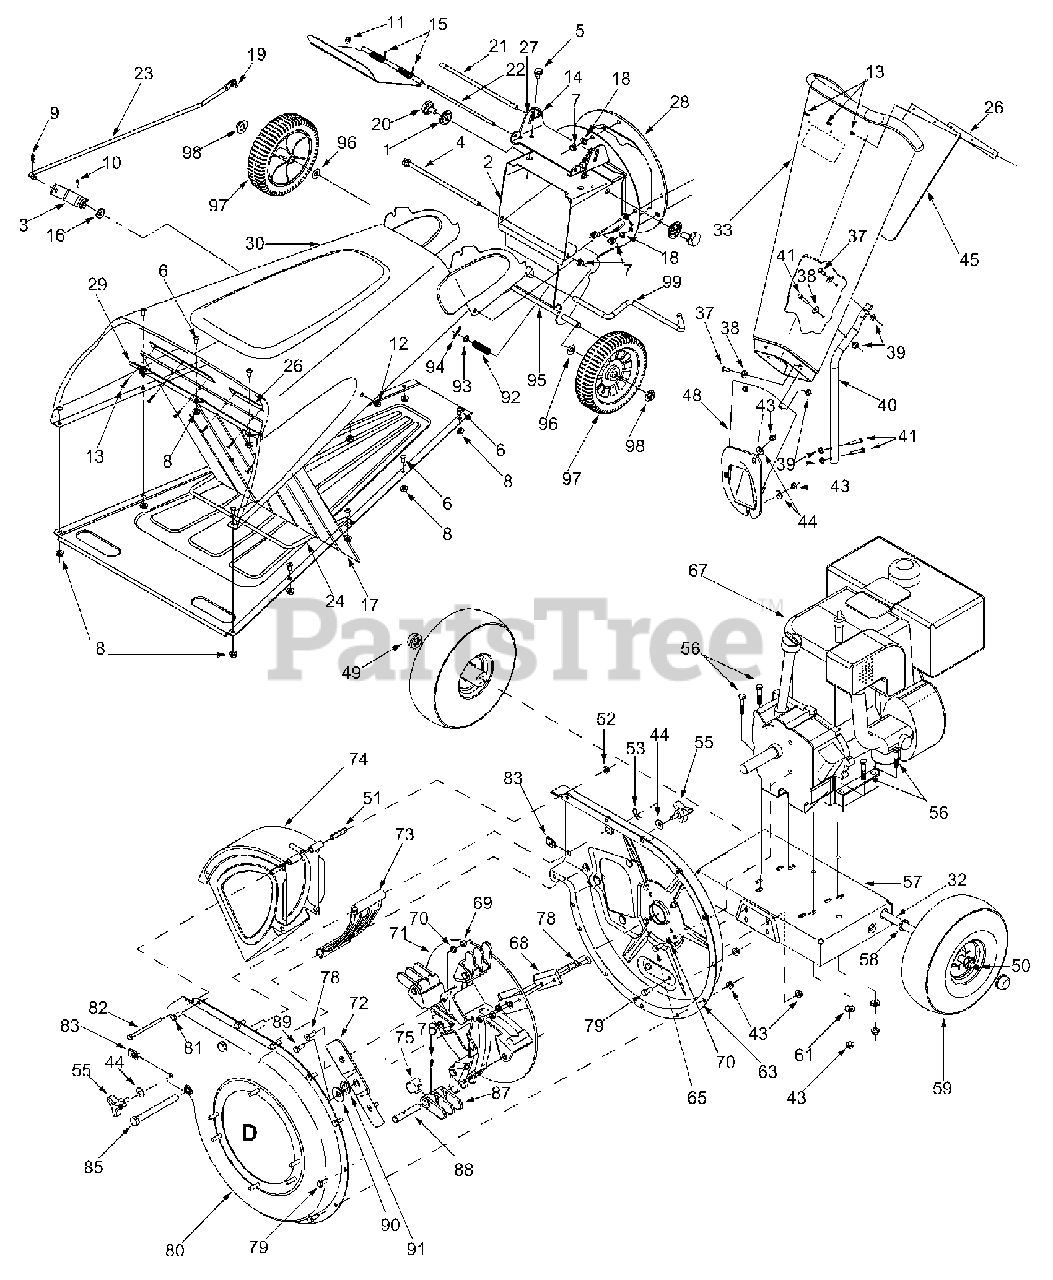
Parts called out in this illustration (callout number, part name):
1	Stop Washer
4	Hex Flange Bolt: 5/16-18 x 8.375" (Gr.5)
5	Hex Washer Head Self-Tapping Screw: 5/16-18 x 0.5"
6	Button-Head Screw 1/4-20 x 0.5"
7	Lock Nut: 5/16-18
8	Hex Flange Lock Nut: 1/4-20
9	Internal Cotter Pin
10	Spiral Pin
11	Cap Nut
12	Speed Cap Nut
13	Pop Rivet
14	Torsion Spring
15	Hopper Door Spring
16	Rubber Washer
17	Hopper Flap
18	Lock Washer
19	Shdr. Scr: .340 x .285 x 1/4-20
20	Shdr. Scr: .56 x .165 x 5/16-18
21	Rel. Rod: 5/16" dia.
22	Hopper Door Rod
23	Flap Retaining Rod
24	Flap Retaining Bail
32	Shredder Axle
33	Chipper Chute
37	Hex Bolt 1/4-20 x .625
38	Flat Washer .28 I.d. x .74 O.d.
39	Flanged Lock Nut
41	Hex Scr. 1/4-20 x .625 (Gr. 2)
43	Hex Nut 5/16-18 Thd. (Gr. 5)
44	Bell Washer .345" I.d. x .88"
45	Shredder Chute Flap
48	Chipper Chute Assembly
49	Push Cap 5/8" dia.
50	Air Valve
51	Chute Hinge Spacer
52	Hex Ctr. Lock Nut 1/4-20 Thd.
53	Internal Cotter Pin
55	Hand Knob
56	Hex Bolt 5/16-18 x 1.5"
58	Flat Washer 1.12 x .64 x .120
59	Wheel Assembly
61	Special Lock Washer
63	Flail Housing Ass'y. - Inner
65	Hex Bolt 5/16-24 x .75" Lg.
68	Chipper Blade
69	Hex Top Lock Nut 5/16-24 (Gr. 5)
70	Lock Washer 5/16" I.d.
71	Impeller assembly
72	Shredder Blade
73	Shredder Screen
75	Retaining Clip
76	Spring Roll Pin
78	Flat Head Scr. 5/16-24 x .75"
79	Hex Bolt 5/16-18 x .75" (Gr. 5)
80	Flail Housing Ass'y. - Outer
82	Hex Bolt 1/4-20 x 3.75"
83	U Nut 5/16-18
85	Clevis Pin
87	Flail Blade
88	Clevis Pin
89	Hex Patch Bolt 3/8-24 x 2.25" (Gr. 8)
90	Lock Washer 3/8"
91	Flat Washer .406" I.d. x 1.25"
92	Compression Spring
93	Flat Washer
94	Internal Cotter Pin
95	Axle Shaft
96	Flat Washer
97	Complete Wheel: Grey
98	Push Cap
99	Lock Rod
